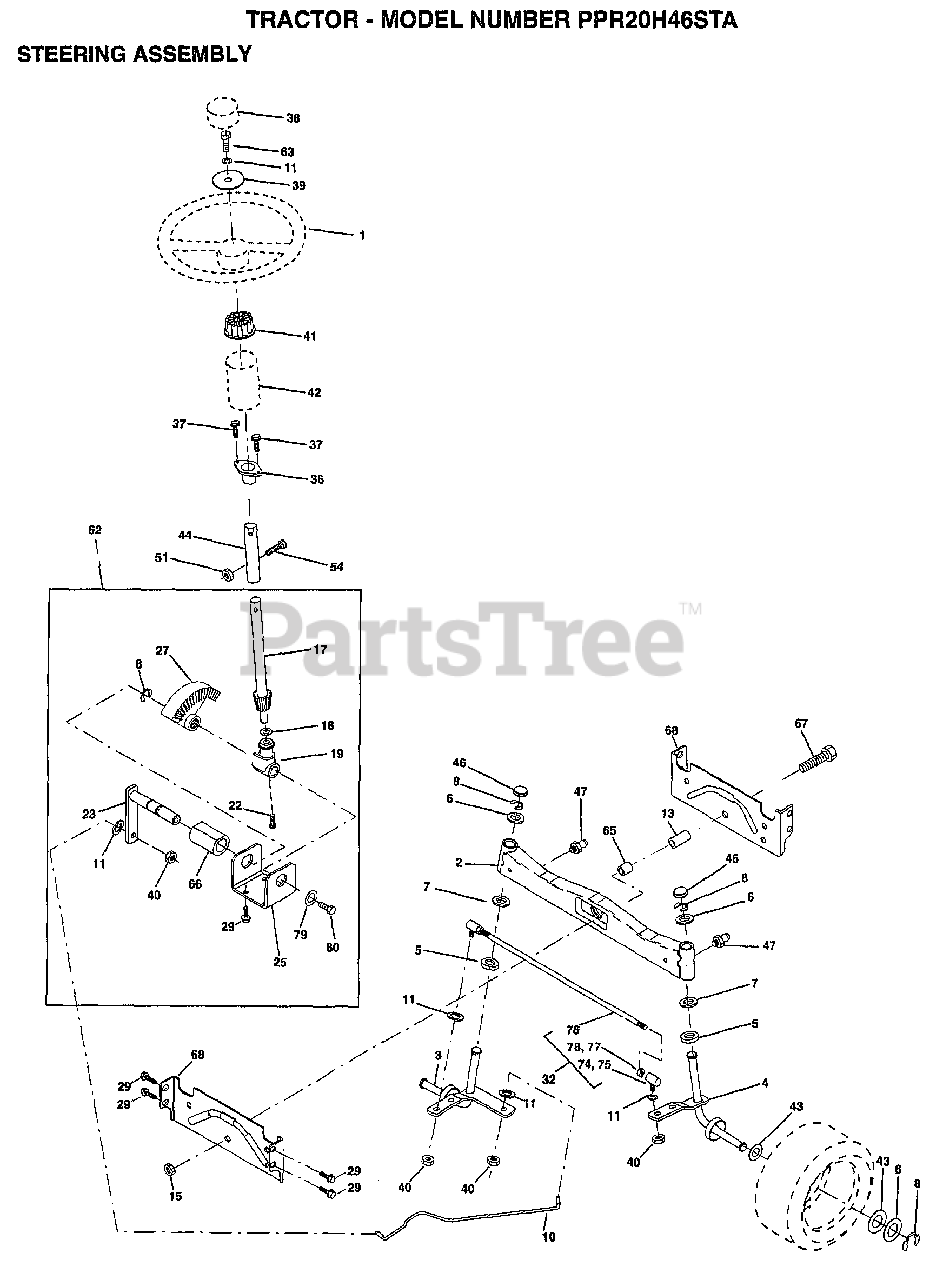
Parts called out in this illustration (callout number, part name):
3	"SPINDLE ASM,LH"
4	"SPINDLE ASM,RH"
5	WASHER .T
6	WASHER
7	WASHER
8	RING
10	LINK.DRAG
11	LOCKWASHER
13	BEARING.FRT.SPACER.AXLE
15	"NUT-LOC,FLANGE LT"
17	SHAFT ASM STEERIN
18	THRUST WASHER
19	SUPPORT.SHAFT.STEER
22	SCREW.HX.WSH.HD
23	SHAFT.ASM.PITMAN
25	BRKT-STEERING
27	GEAR SECTOR
29	SCREW
32	ROD.ASM.TIE.BALL
36	BUSHING.STEERING
37	"SCREW-TT,10-32 FL"
38	"INSERT,STR WHEEL"
39	WASHER T
40	GRIPCO NUT
41	ADAPTER LT
42	BOOT.STEER.PL
43	WASHER
44	EXT SHAFT STEERIN
46	CAP
47	ZERK M
51	NUT
54	BOLT
62	KIT.STEER.ASM
63	BOLT
65	SPACER AXLE
66	"BEARING-ARM,PITMA"
67	BOLT
68	BRACE AXLE
74	JOINT.RH
75	JOINT.LH
77	NUT
78	NUT
79	WASHER
80	BOLT.HX.NYLON3/8-16X3/
